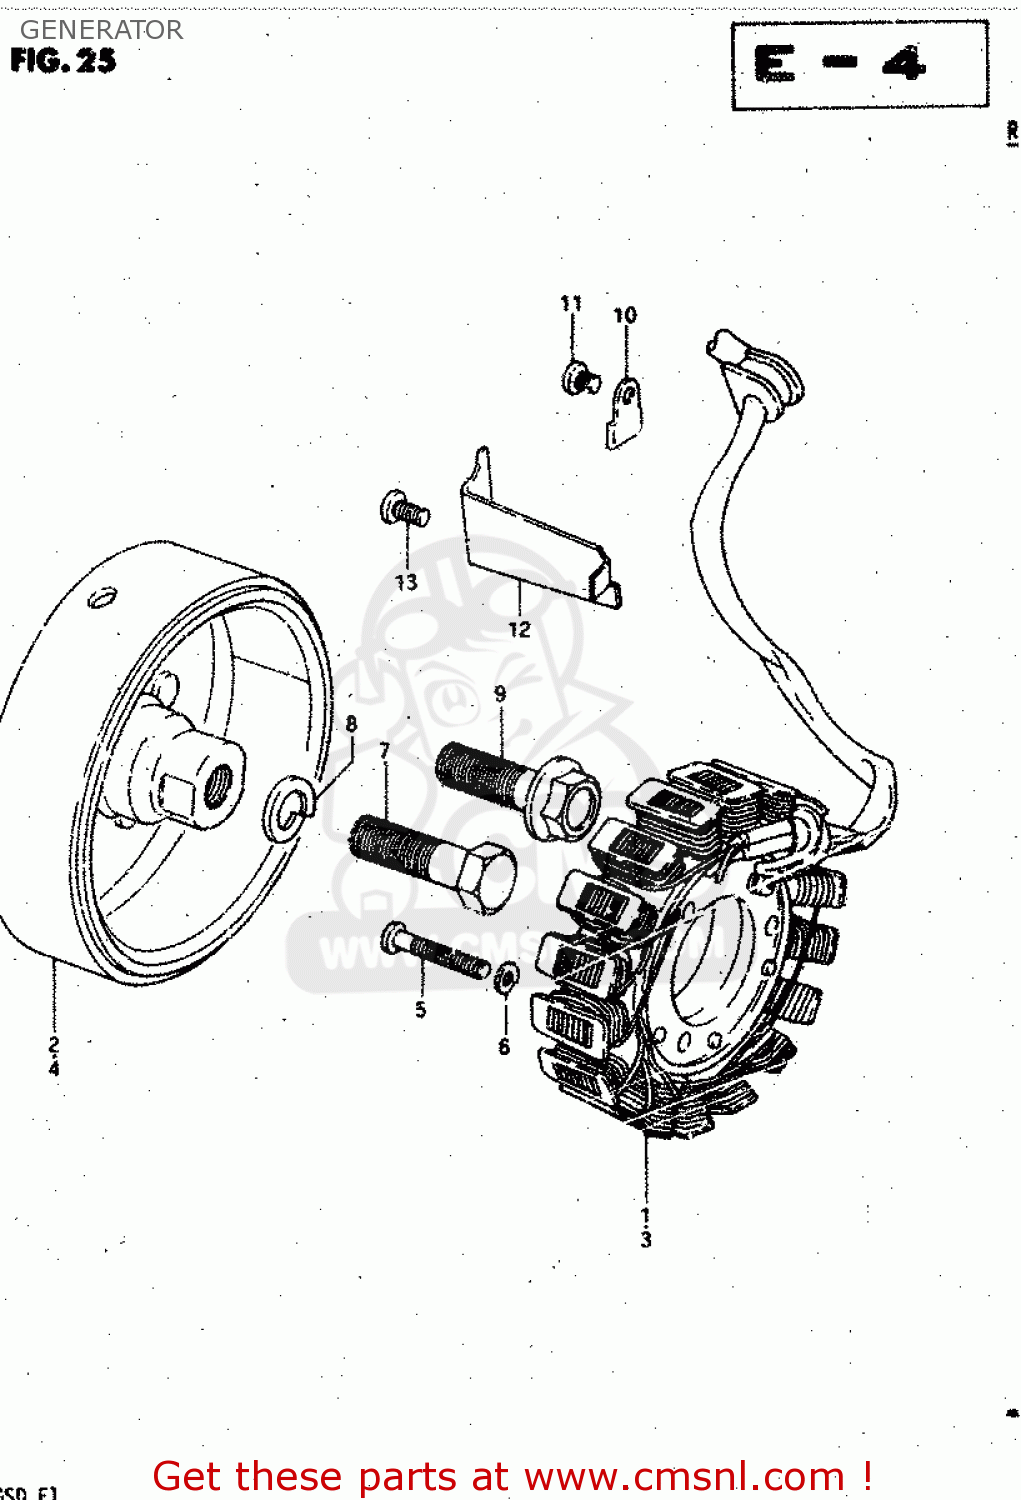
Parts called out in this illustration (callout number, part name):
1	STATOR ASSEMBLY
2	ROTOR ASSEMBLY
3	STARTER ASSY
4	ROTOR ASSEMBLY
5	SCREW
6	LOCK WASHER
7	BOLT 12X45
8	WASHER,LOCK 12
9	BOLT(12X40)
10	CLAMP,GENERATOR LEAD WIRE
11	SCREW
12	CLAMP,GENERATOR LEAD WIRE
13	SCREW
